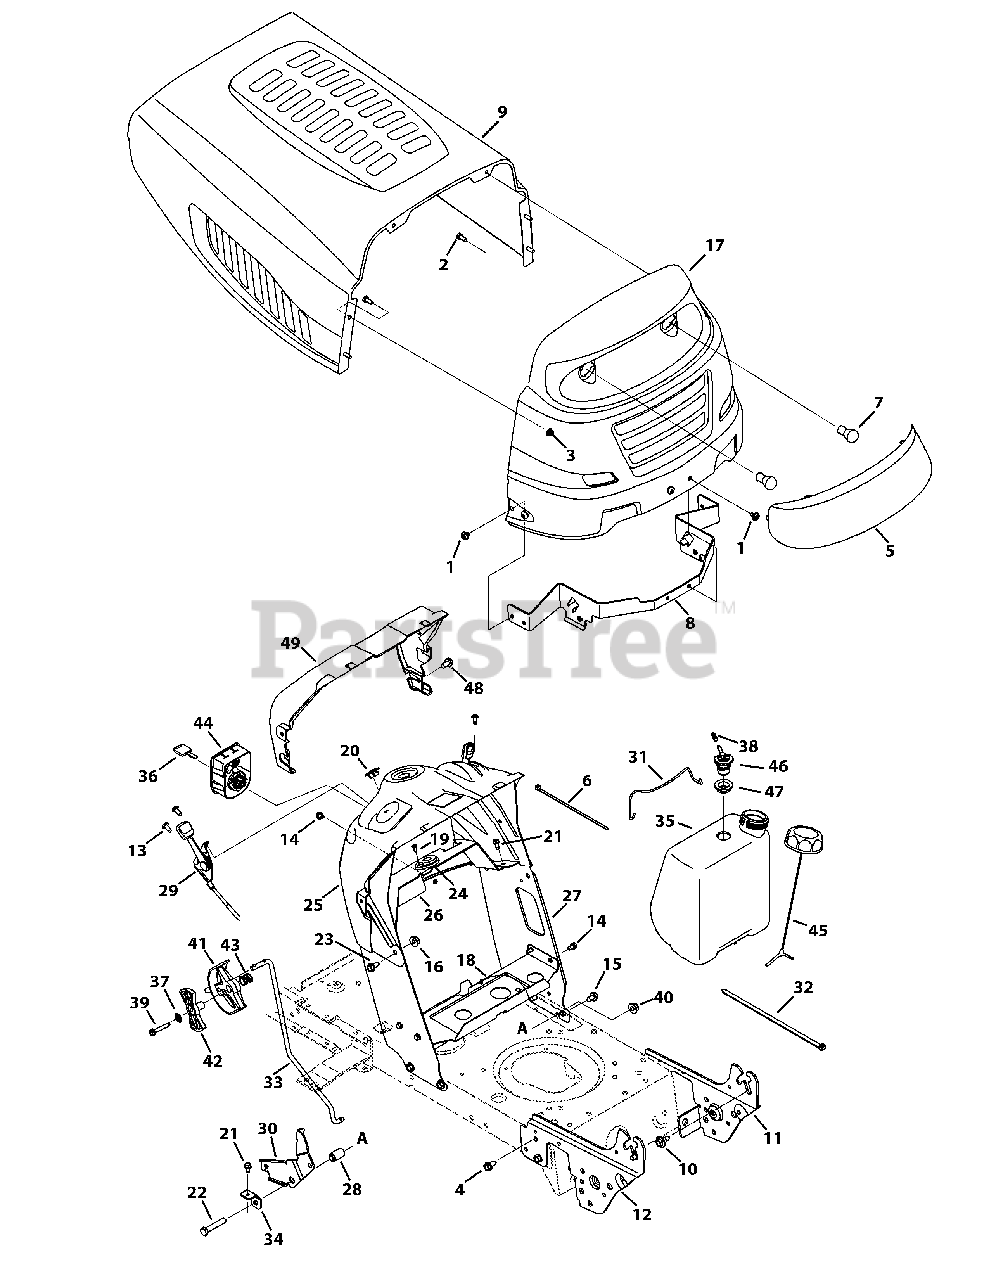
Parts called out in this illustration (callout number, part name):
1	Screw, 5/16-18 x .375
2	Hex Screw, 1/4-20 x .620
3	Flangelock Nut, 1/4-20
4	Screw, 5/16-18 x .750
5	Grill Lens
6	Cable Tie
8	Hood Pivot Bracket
9	Hood - Red
9	Hood - Black
10	Shoulder Screw, 5/16-18 x .43 x .29
11	Left Support Pivot Bracket
12	Right Support Pivot Bracket
13	Screw, 1/4-20 x .500
14	Screw, 1/4-20 x .500
15	Screw, 5/16-18 x .625
16	Flangelock Nut, 5/16-18
17	Grill - Red
17	Grill - Black
18	Gas Tank Support Bracket
19	Screw, #10-16 x .500
20	Choke Plug
21	Tap Screw, 1/4-20, 0.625
22	Hex Screw, 3/8-16 x 2.0
23	Hex Screw, 5/16-18 x .625
24	Bearing, .628 ID x 1.36
25	Dash, Upper
25	Dash, Upper, No RMC
26	Bracket, Steering Support
27	Dash, Lower
28	Flange Spacer, .390 x .671 x 1.095
29	Throttle/Choke Cable
31	Battery Assembly Rod
32	Cable Tie
33	Speed Control Rod
34	Speed Latch Tab
35	136 Gallon Fuel Tank
37	Lock Washerer, 1/4
38	Hose Vent, 3/16 (EPA)
39	Hex Washerer Screw, 1/4-20 x 1.50
40	Flangelock Nut, 3/8-16
41	Shift Lever
42	Index Control
43	Compr Spring, .72 OD x .78
44	3 Position Key Switch
45	Fuel Cap, 2.25"
46	Rollover Valve
47	Rubber Grommet, 23 x 3.55
48	Screw, 1/4-15 x .750
49	Dash Collar
